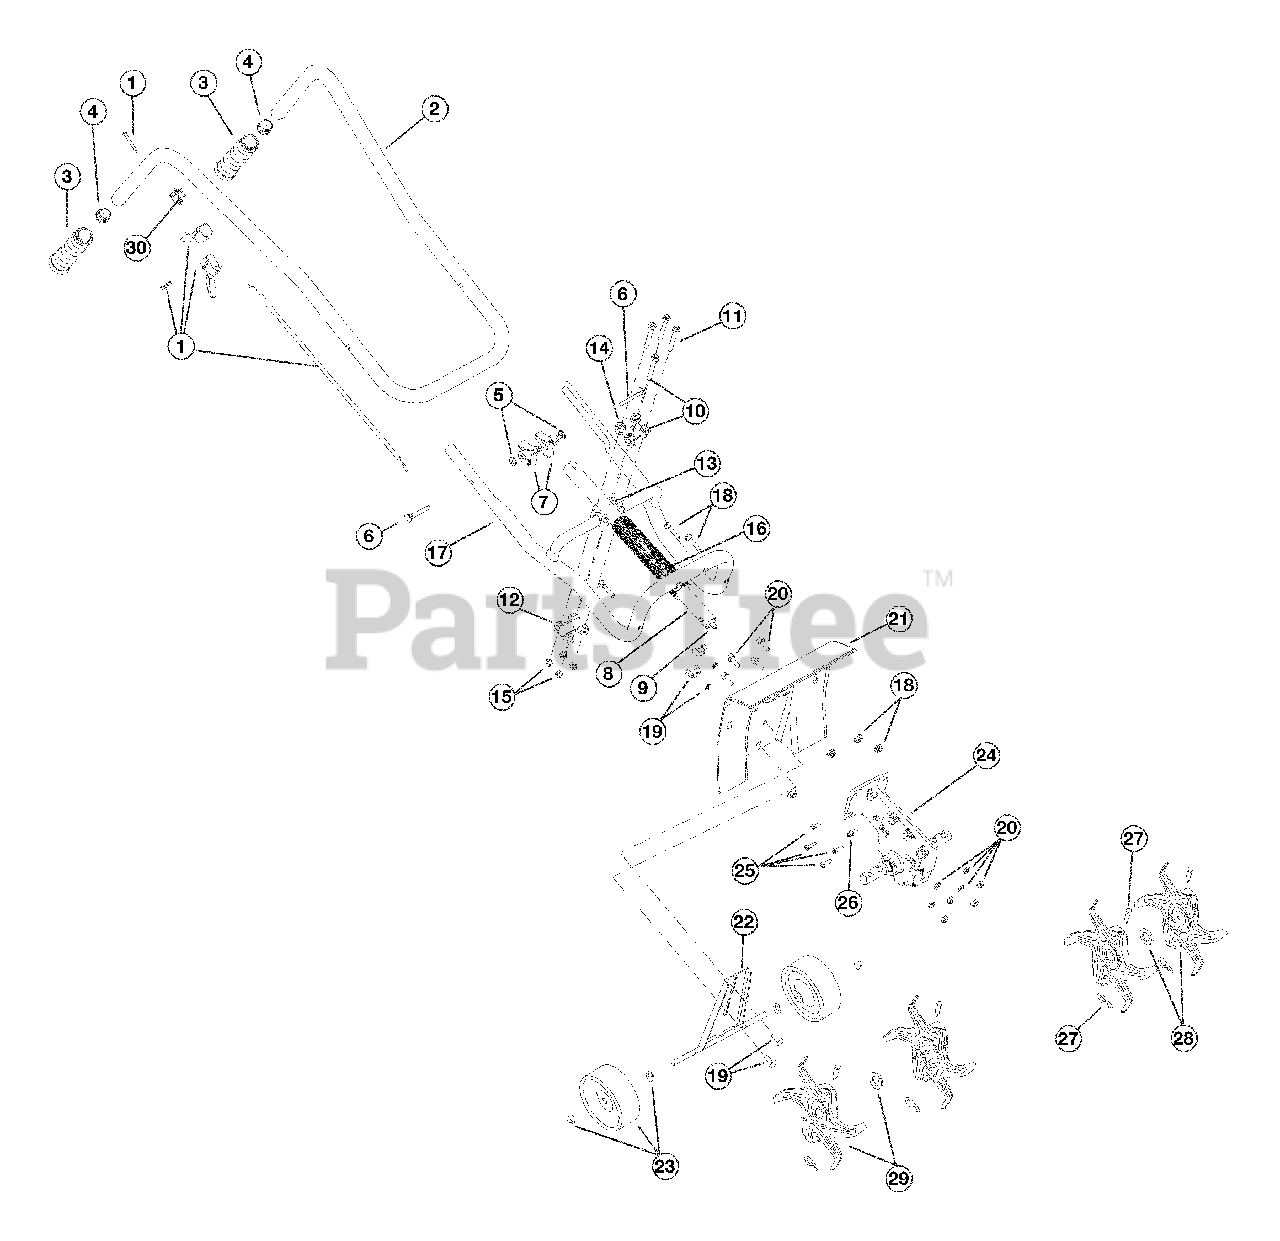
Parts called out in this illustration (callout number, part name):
1	Throttle Trigger and Cable Assembly
2	Handle Bar Assembliy, Upper
4	Tube Closure
5	Washer
7	Knob, 3 prong
8	Drive Shaft Housing Assembly
9	Flexible Drive Shaft
10	Handle Bracket Assembly
12	Upper Handle Clamp
13	Middle Handle Clamp
14	Lower Handle Clamp
17	Lower Handle Bar
18	Hardware, Handle Bar Mounting (lower)
19	Wheel Bracket Mounting Hardware
20	Guard Mounting Hardware
22	Wheel Bracket Assembly
23	Wheel Assembly
24	Gear Box Assembly
26	Sleeve Retainer Bolt
27	Tine Fastener Assembly
28	Tine Assembly (Left Outer or Right Inner)
29	Tine Assembly (Left Inner or Right Outer)
